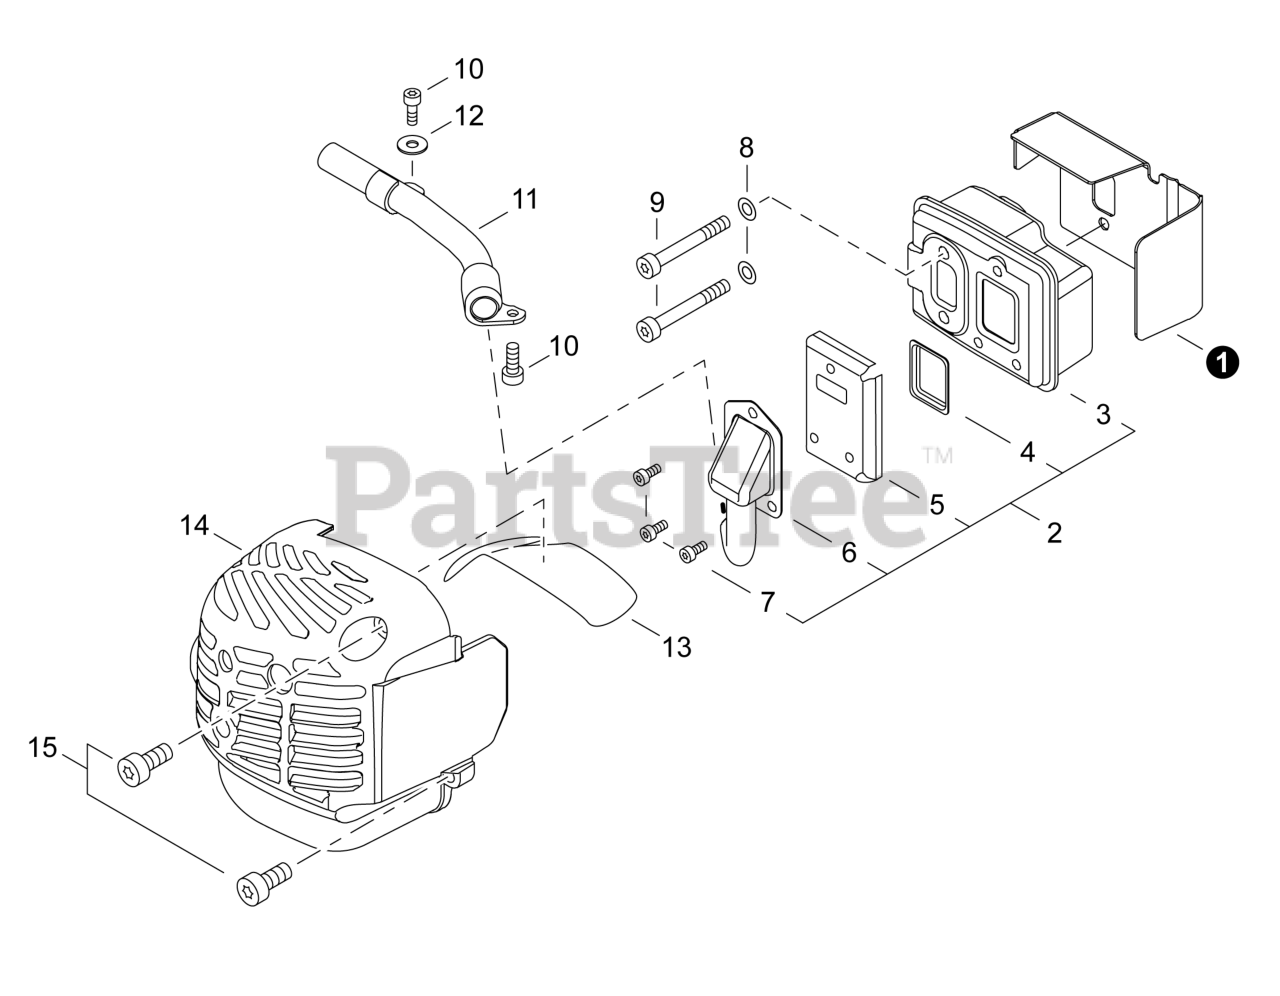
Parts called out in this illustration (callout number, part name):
1	HEAT SHIELD, EXHAUST
2	MUFFLER ASSY
3	MUFFLER
4	SCREEN, SPARK ARRESTER
5	GASKET, EXHAUST
6	GUIDE, EXHAUST
7	BOLT, TORX 4x8
8	WASHER 5.5x12x0.8
9	BOLT, TORX 5x55
10	BOLT, TORX 5x10
11	GUIDE, EXHAUST
12	WASHER 5
13	PLATE, INSULATOR
14	COVER, MUFFLER
15	BOLT, TORX 5x16
